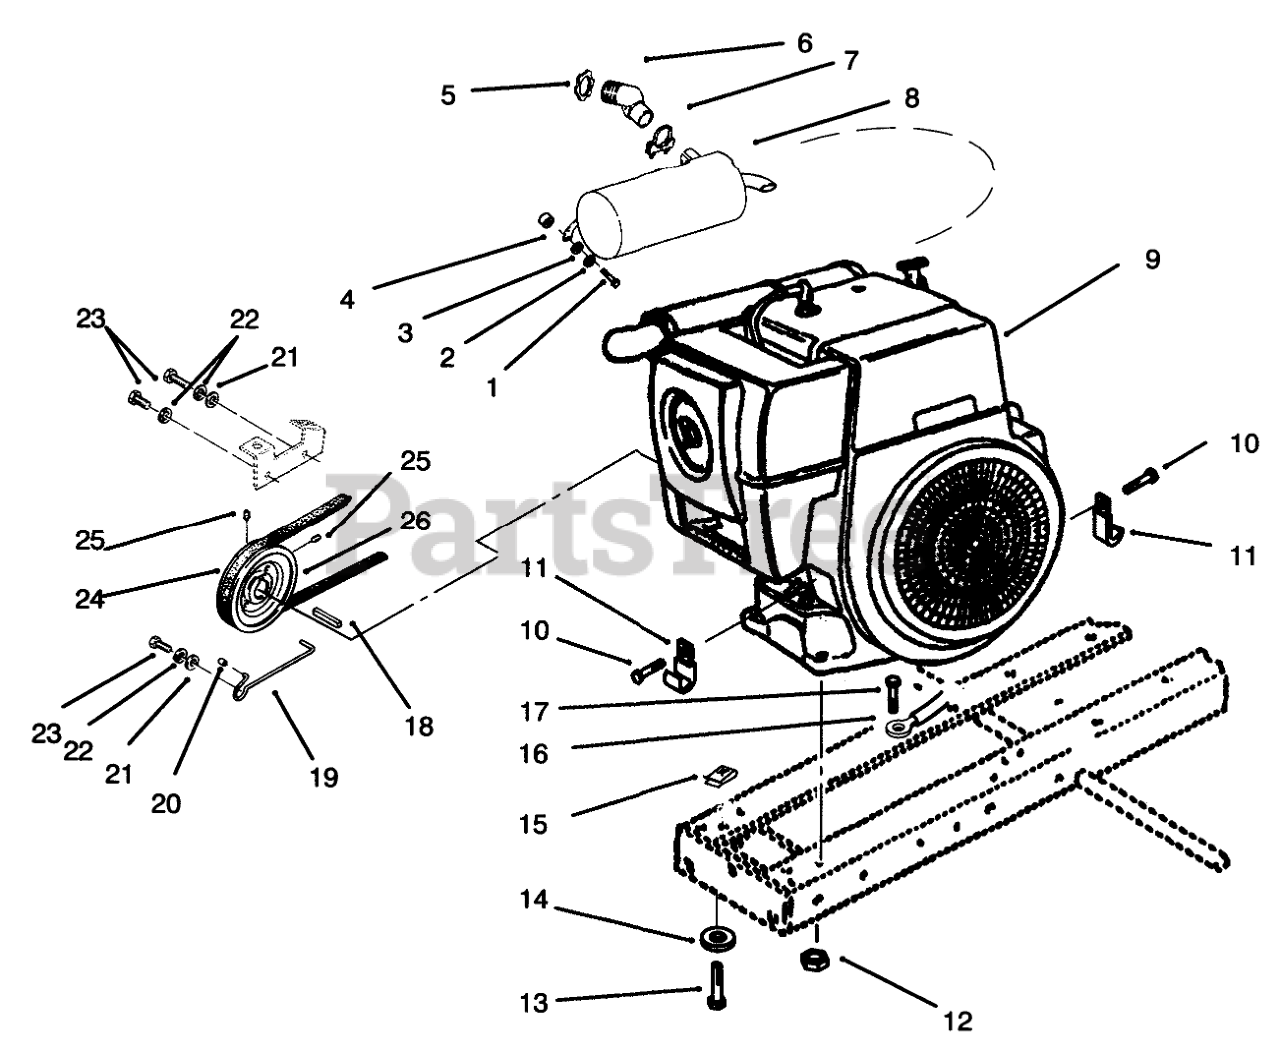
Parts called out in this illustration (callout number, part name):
1	SCREW-HH
2	WASHER-LOCK
3	WASHER-PLAIN
4	SPACER
5	Nut-Lock
6	Elbow
7	CLAMP-1 1/2
8	Muffler
9	Engine-14HP
10	Screw (Engine) Ref
11	CLIP
12	NUT-LOCK, NI
13	SCREW-HH
14	WASHER-LOCK
15	SPEED CLIP
16	WIRE GROUND
17	SCREW-HH
19	GUIDE BELT
21	WASHER-FLAT
22	WASHER-LOCK
23	SCREW-HH
24	V-BELT TRANS DRIVE
25	SCREW-SET, HSH
26	PULLEY
